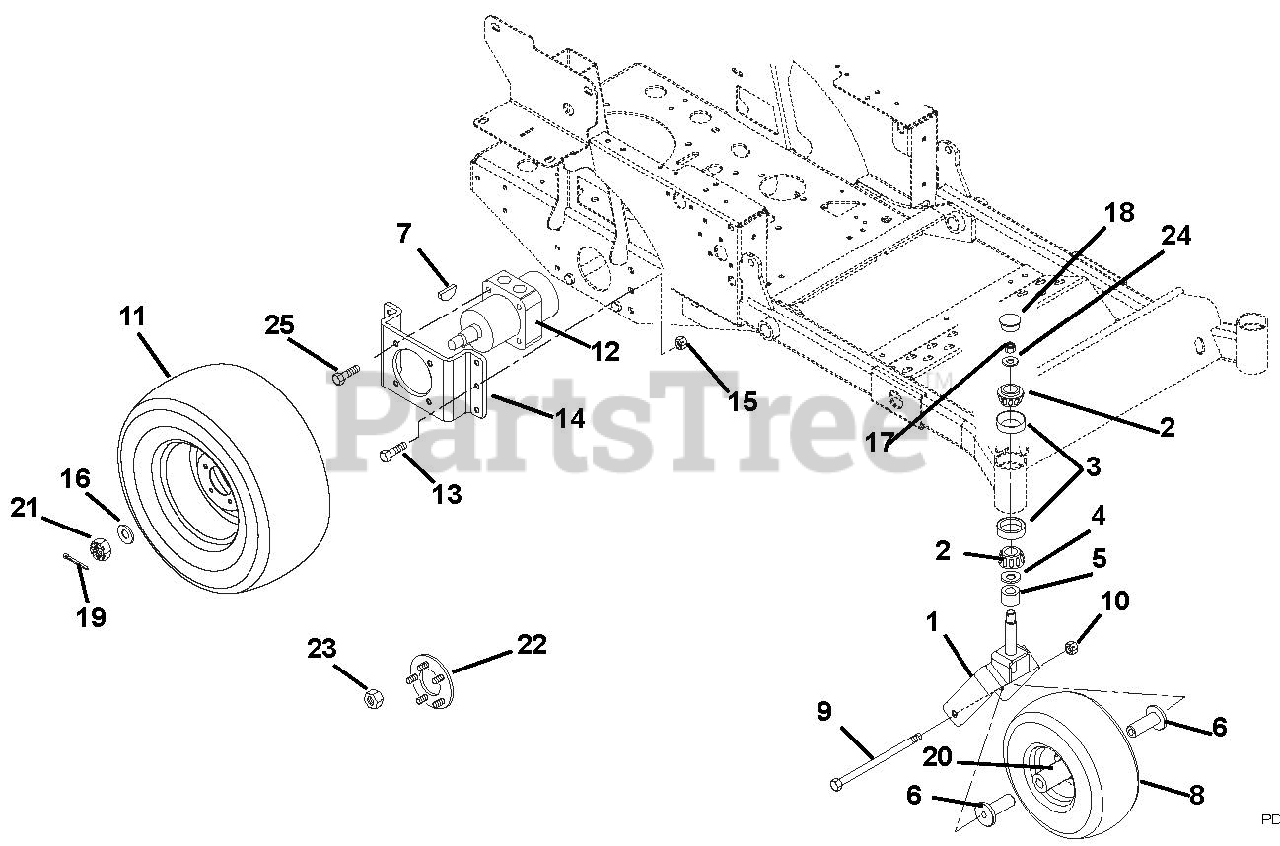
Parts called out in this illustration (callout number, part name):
1	Weldment, Front Fork
2	Bearing, Cone with Grease, 1.0 x .58
3	Bearing, Cup 1.980 x .420
4	Bearing Seal 1.5 x 2 x .18
5	Spacer, PM, 1.03 I.D. x 1.5 O.D. x .375
6	Spacer, Wheel
7	Key, Woodruff .31 x 1.00
8	Wheel/Tire Assembly 5.25 x 13.00
9	Bolt, Hex .50-13 x 7.50 Grade 5
10	Nut, Nyloc Flange .50-13
11	Wheel, Tire Assembly 20 x 10-10
11	Wheel, Tire Assembly 5.25 x 13
11	Tire, 20 x 10.00-NHS Turf Saver
11	Tire, 20 x 10.00 Multi Trac C-S
11	Wheel, Tire 20 x 10-10
11	Tire, 21 x 7.00 Turf Saver
12	Motor, Hydraulic Wheel
13	Bolt, Hex .38-16 x 1.00 Grade 5
14	Bracket, Wheel Motor
15	Nut, Nyloc Flange 3/8-16
16	Washer, Flat Steel .755 x 1.375 x .062
17	Nut, Center Lock Jam .75-16
18	Cap, Dust
19	Pin-Cotter .09 x 1.25 Extended Prong Square Cut
20	Bearing, 25MM I.D. x 52MM OD x 15MM
21	Nut, Hex .75-20
22	Assembly, Service Hub with Studs
22	Assembly, Service Hub with .50 Studs
23	Wheel Nut .50-20
23	Wheel Nut .437-20
24	Washer, Flat, Steel .880 x 1.250 x .062
25	Bolt, Hex .38-16 x 1.00 Grade 8 Epoxy 30
